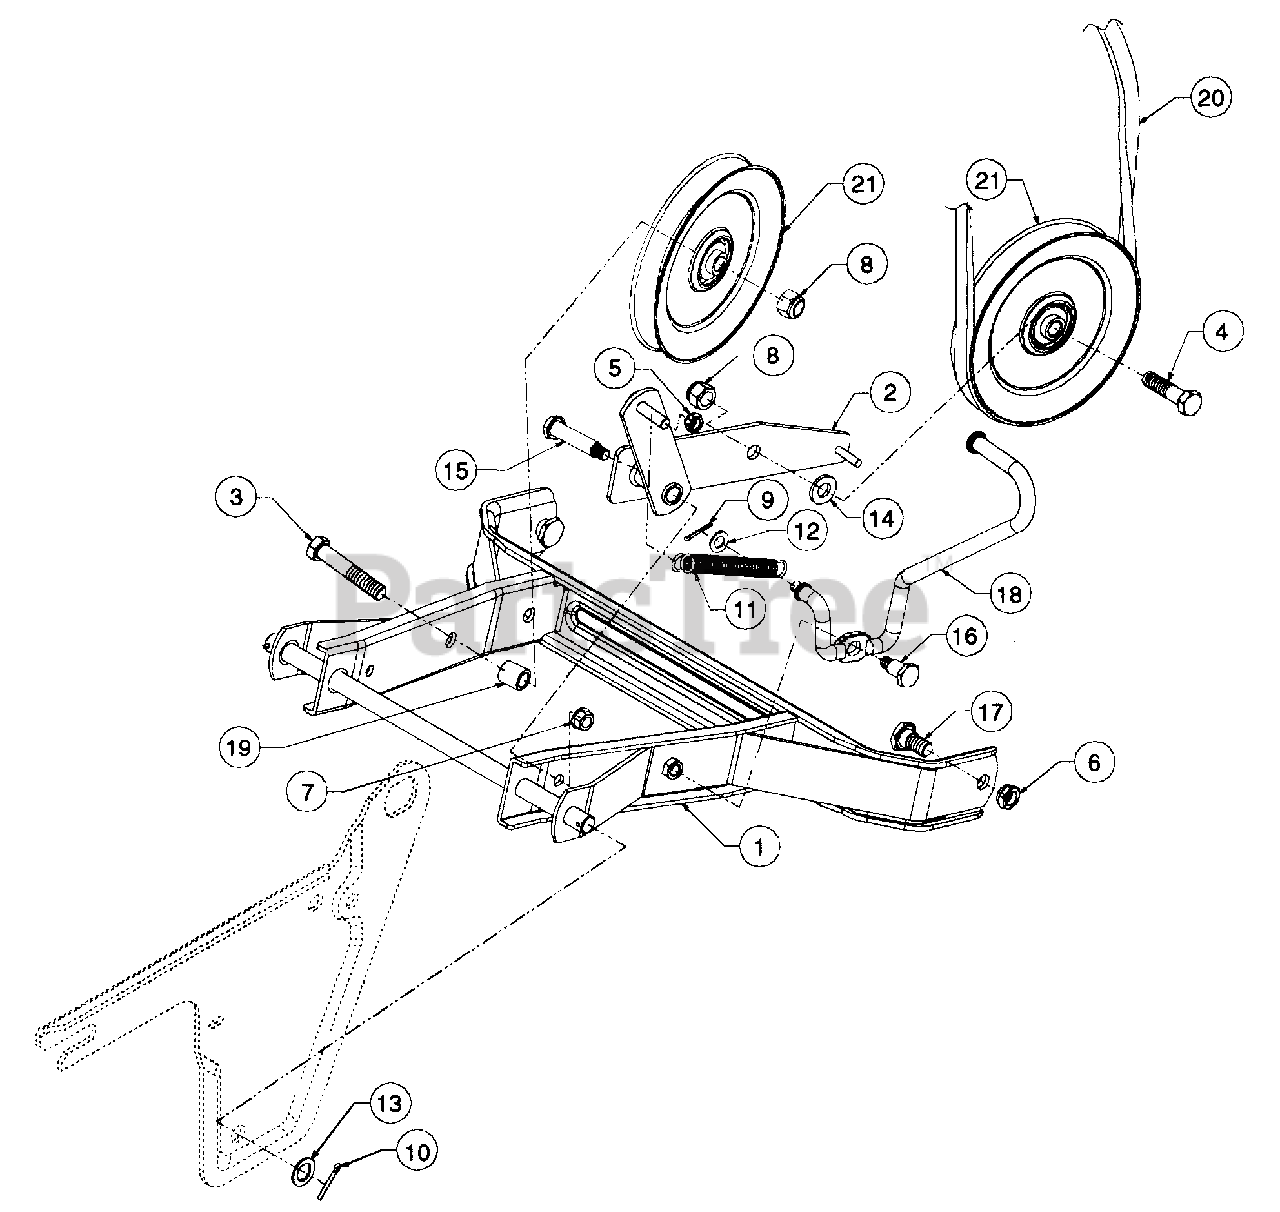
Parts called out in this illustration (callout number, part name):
4	Screw, Hex Cap, 1/2-13 X 2.0 GR8
5	Nut, Hex Insert Lock Jam, 3/8-24
6	Nut, Hex Insert Lock Jam, 1/2-20
7	Nut, Hex Flanged Lock, 3/8-16
8	Nut, Hex Top Nylon Lock, 1/2-13
9	Pin, Cotter, 3/32 X 1.0
10	Pin, Cotter, 1/8 X 1.0
11	Spring, Extension
12	Washer, Flat, .406 X .75 X .063
13	Washer, Flat, 5/8 X 1.0 X .063
14	Washer, Flat, .510 X 1.0 X .125
15	Bolt, Shoulder, .498 Dia X 2.0 Lg
16	Bolt, Shoulder, .498 Dia X .710 Lg
17	Bolt, Shoulder, .62 Dia X .30 Lg
18	Rod, Spring Tension
19	Spacer, .501 X .75 X .78
20	V-Belt, 5/8 X 89 Lg
21	Pulley, V-Idler, 7.0 OD
